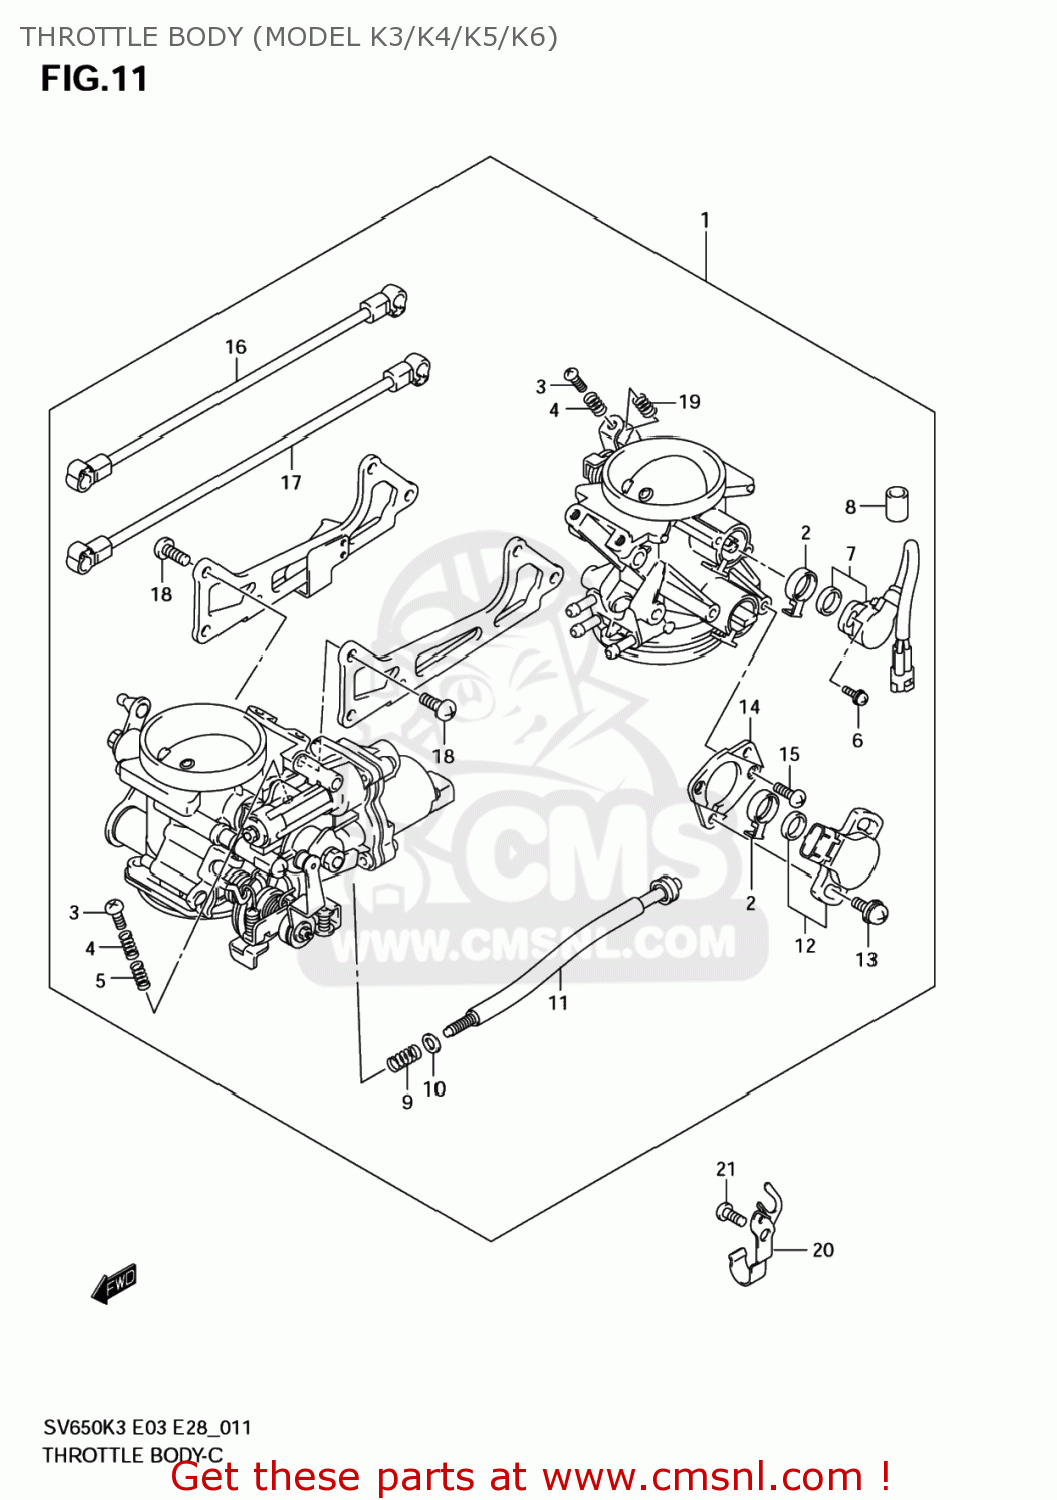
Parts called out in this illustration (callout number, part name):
1	THROTTLE BODY
2	RING
3	SCREW
4	SPRING
5	SPRING,THROTTLE SCREW
6	SCREW
7	SENSOR ASSY
8	HOSE
9	SPRING
10	WASHER
11	SCREW ASSY,ADJUST
12	SENSOR ASSY,THROTTLE
13	SCREW
14	PLATE
15	SCREW
16	ROD ASSY
17	ROD ASSY
18	SCREW
19	SPRING
20	PLATE,IDLE ADJUST
21	BOLT
